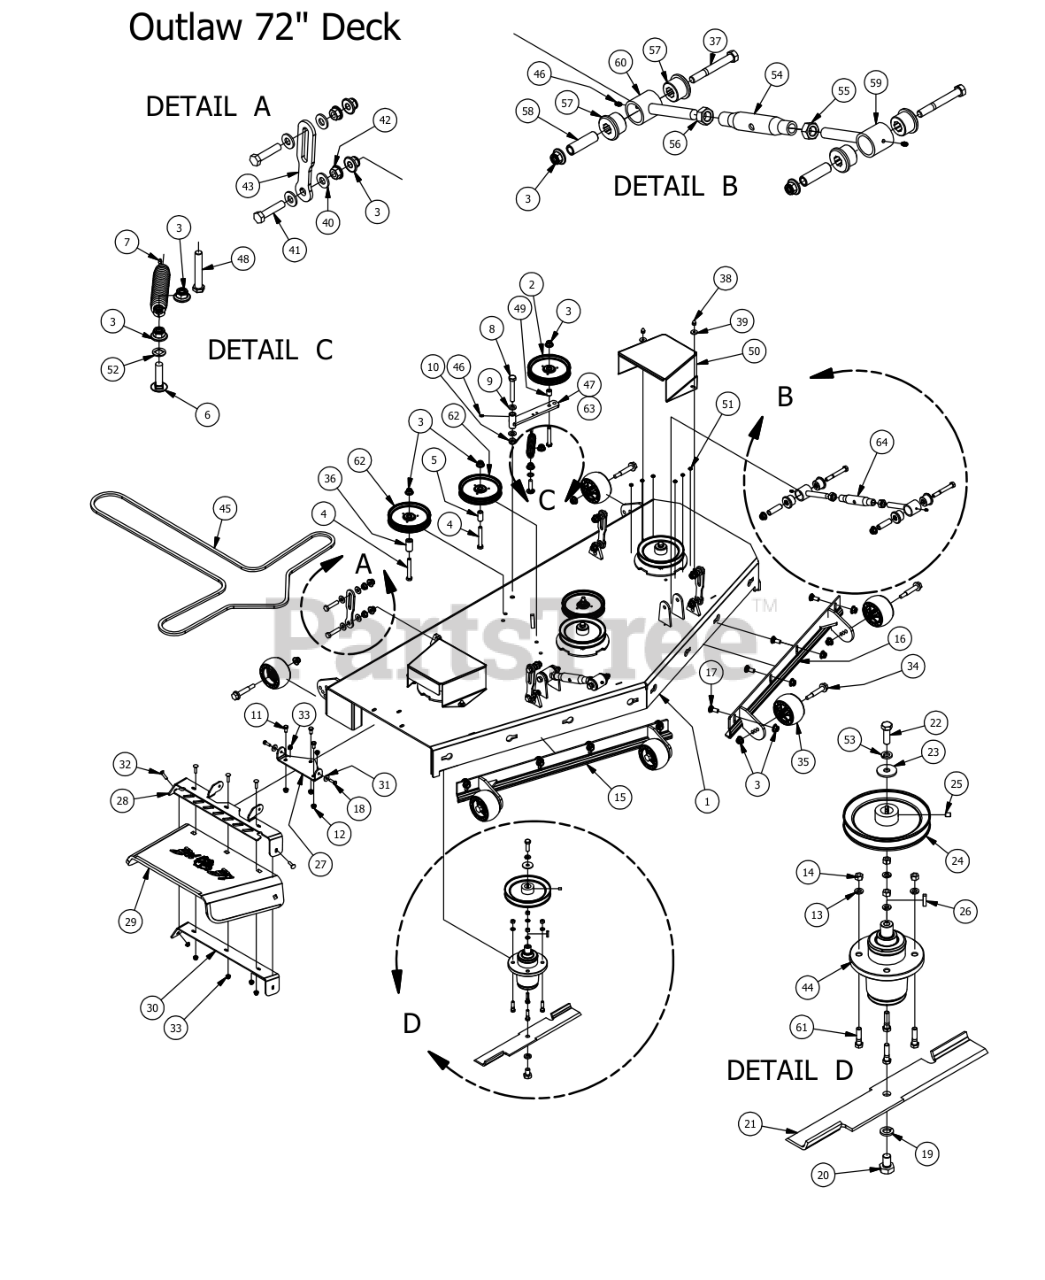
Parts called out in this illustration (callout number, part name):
1	2015 72" Deck
2	5-3/4 Idler Pulley-Don Dye
3	1/2-13 Nylon Flange Nut
4	1/2 x 3 1/2 Flange Bolt Grade 8
5	.502 ID X.750 OD X 1.500 Long Spacer
6	1/2 x 2" Carriage Bolt
7	2015 Deck Idler Spring Outlaws
8	5/8" x 4" Hex Bolt
9	.630 ID Plastic Washer
10	5/8-11 Nylon Insert Jam Half Nut
11	3/8" x 3/4" Hex Bolt
12	3/8" Flange Nut
13	3/8 Lockwasher Zinc
14	3/8-16 Hex Nuts Zinc
15	72" Deck Adustable Front (Right)
16	72" Deck Adjustable Front (Left)
17	1/2" x 1 1/4 Carriage Bolt
18	5/16" x 1" Bolt
19	5/8" Lock Washer
20	5/8" x 1 1/2" Grade 8 Hex Bolt (Fine)
21	72" High Lift Fusion Blade
22	1/2"-20 x 1 1/2 - Grade 5 Fine Thread Bolt
23	1/2 Belleville Washer
24	7" Deck Pulley
25	5/16 Set Screw
26	1/4" x 1" Key
27	Discharge Chute Hanger (deck mounted)
28	60" Discharge Chute Upper Hanger
29	Rubber Discharge Chute
30	60" Discharge Lower Bracket
31	.360 ID Plastic Washer
32	5/16" x 1 1/4" Carriage Bolt
33	5/16" Nylock Flange Nut Zinc
34	Deck Wheel Bolt
35	Anti-Scalp Rollers
36	1 3/4" Pulley Spacer
37	1/2" x 4" Bolt (Grade 8)
38	Acorn nut-pulley Cover
39	.360 ID Plastic Washer-Black
40	.505 Nylon Spacer
41	1/2-13X 2-1/4 GR Hex Bolts
42	1/2" Flange Nut
43	Deck_Hanging Tab
44	OUTLAW SPINDLE ASSEMBLY
45	B202 Belt for 72" Outlaw
46	1/4" Press in Grease Fitting
47	Deck Idler
48	1/2-13 x GR 5 Hex Bolt Zinc
49	Spacer 3/4 OD x 1/2 ID x 3\4 Length
50	72 Spindle Cover
51	Black, Round Stick-On Rubber Bumpon
52	.517 Square Hole Round Washer
53	1/2" Lock Washer
54	2015 Outlaw Toplink Body
55	3/4-10 Left-Handed Hex Nuts Zinc
56	3/4-10 Hex Nuts Zinc
59	Turn Left-Handed
60	Right-Handed End
61	3/8" x 1 1/2" Hex Bolt
62	5-3/4 Idler Pulley-Capitol Stampings
63	Deck Idler Assembly - Includes parts: 2,3,47,48,49
64	Turnbuckle Assembly
